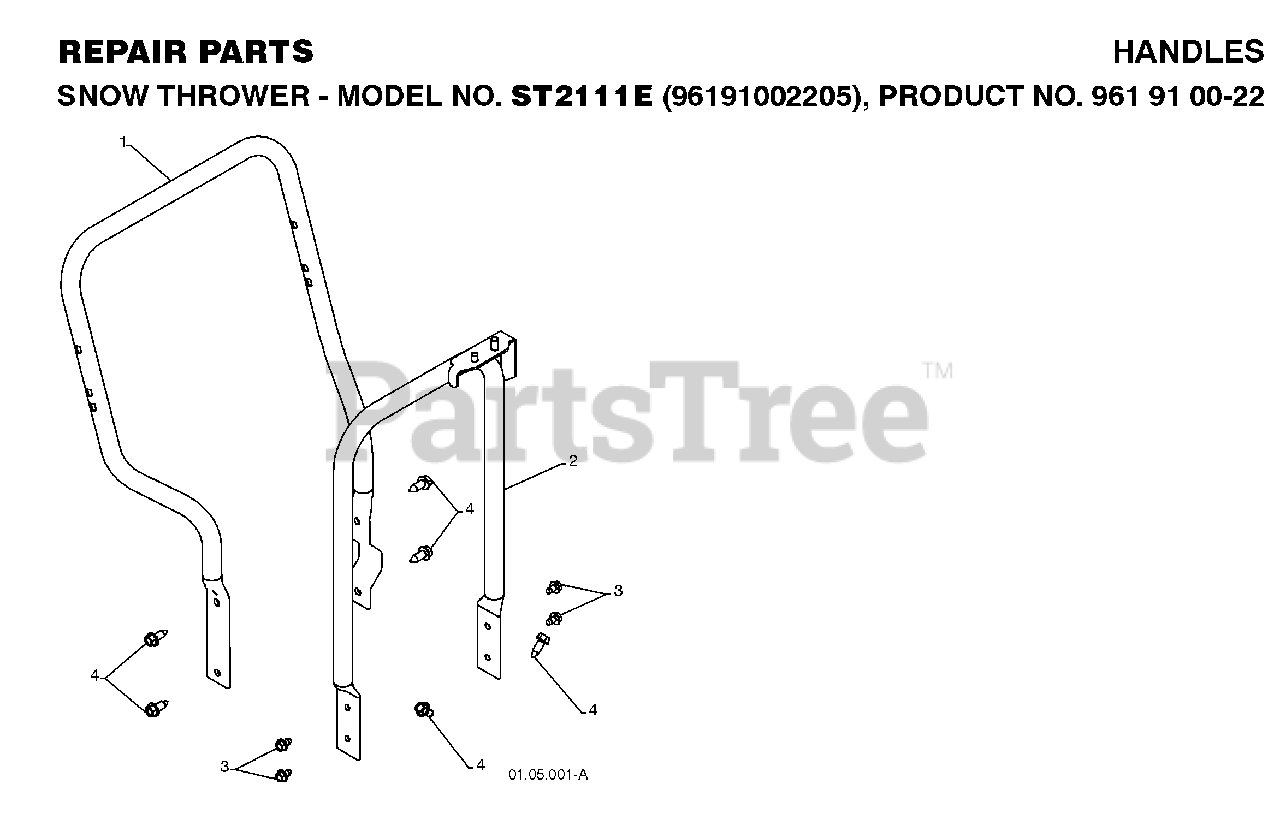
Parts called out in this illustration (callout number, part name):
1	TUBE.LOWER.BLACK
2	SUPPORT, PIVOT
3	SCREW LT
4	SCREW 3/8-16X1
